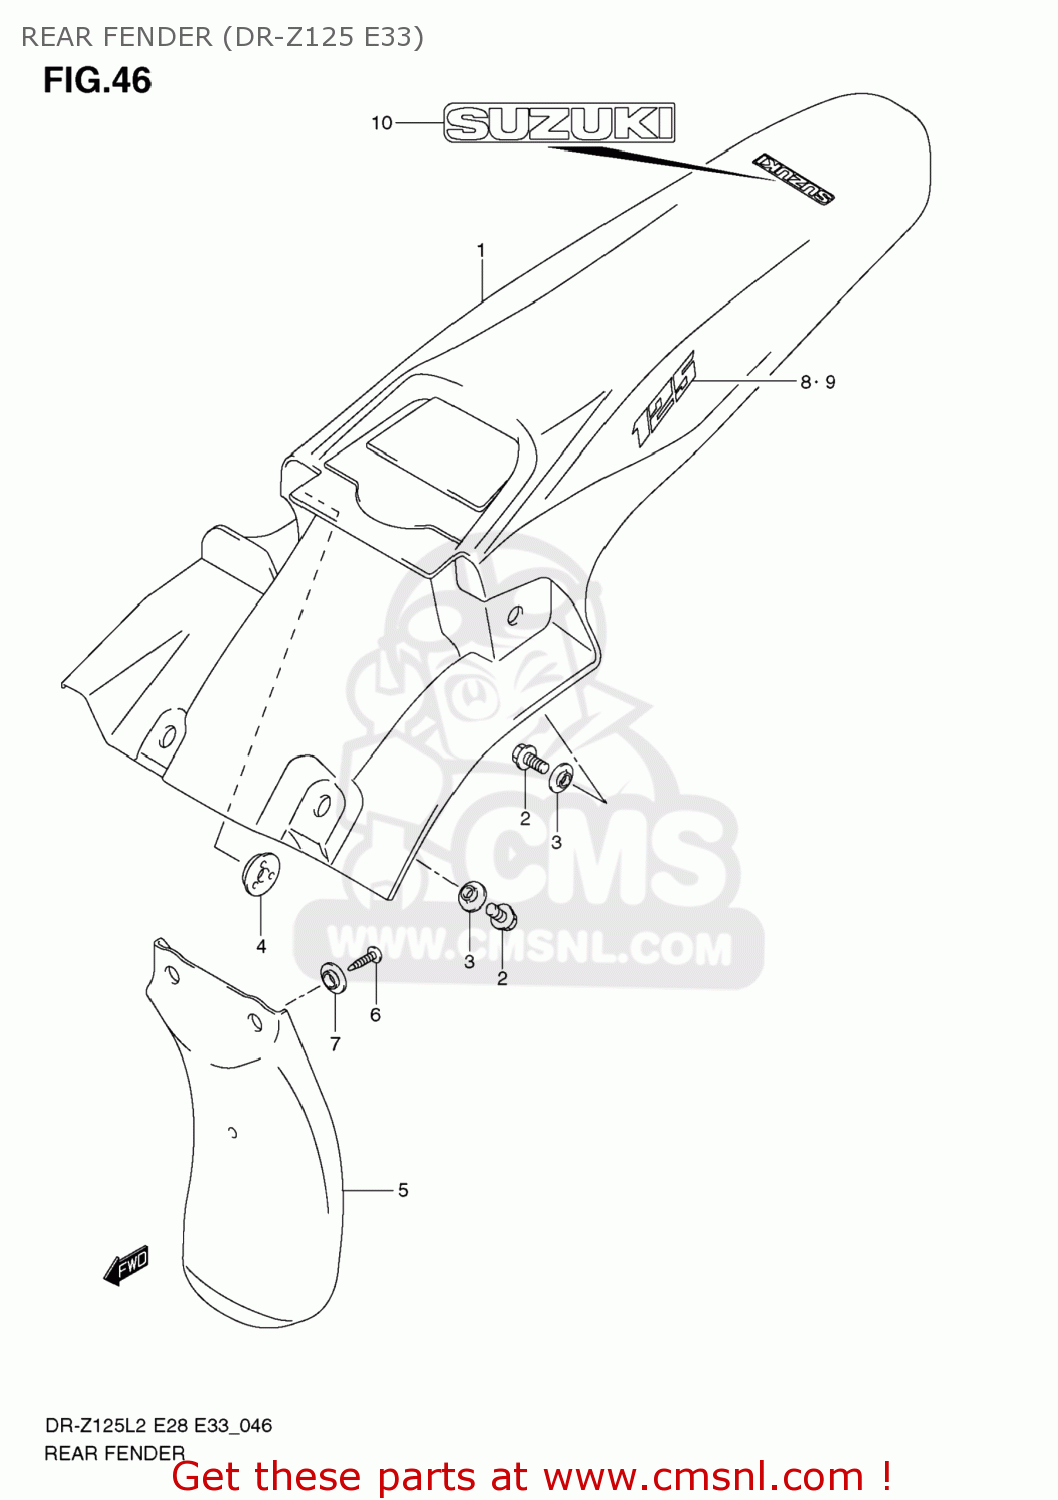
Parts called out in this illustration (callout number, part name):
1	FENDER,RR
2	BOLT(6X16)
3	WASHER
4	WASHER
5	MUDGUARD,RR FENDER FR
6	SCREW(5X16)
7	WASHER
8	EMBLEM,125,R
9	EMBLEM,125,L
10	EMBLEM,SUZUKI
